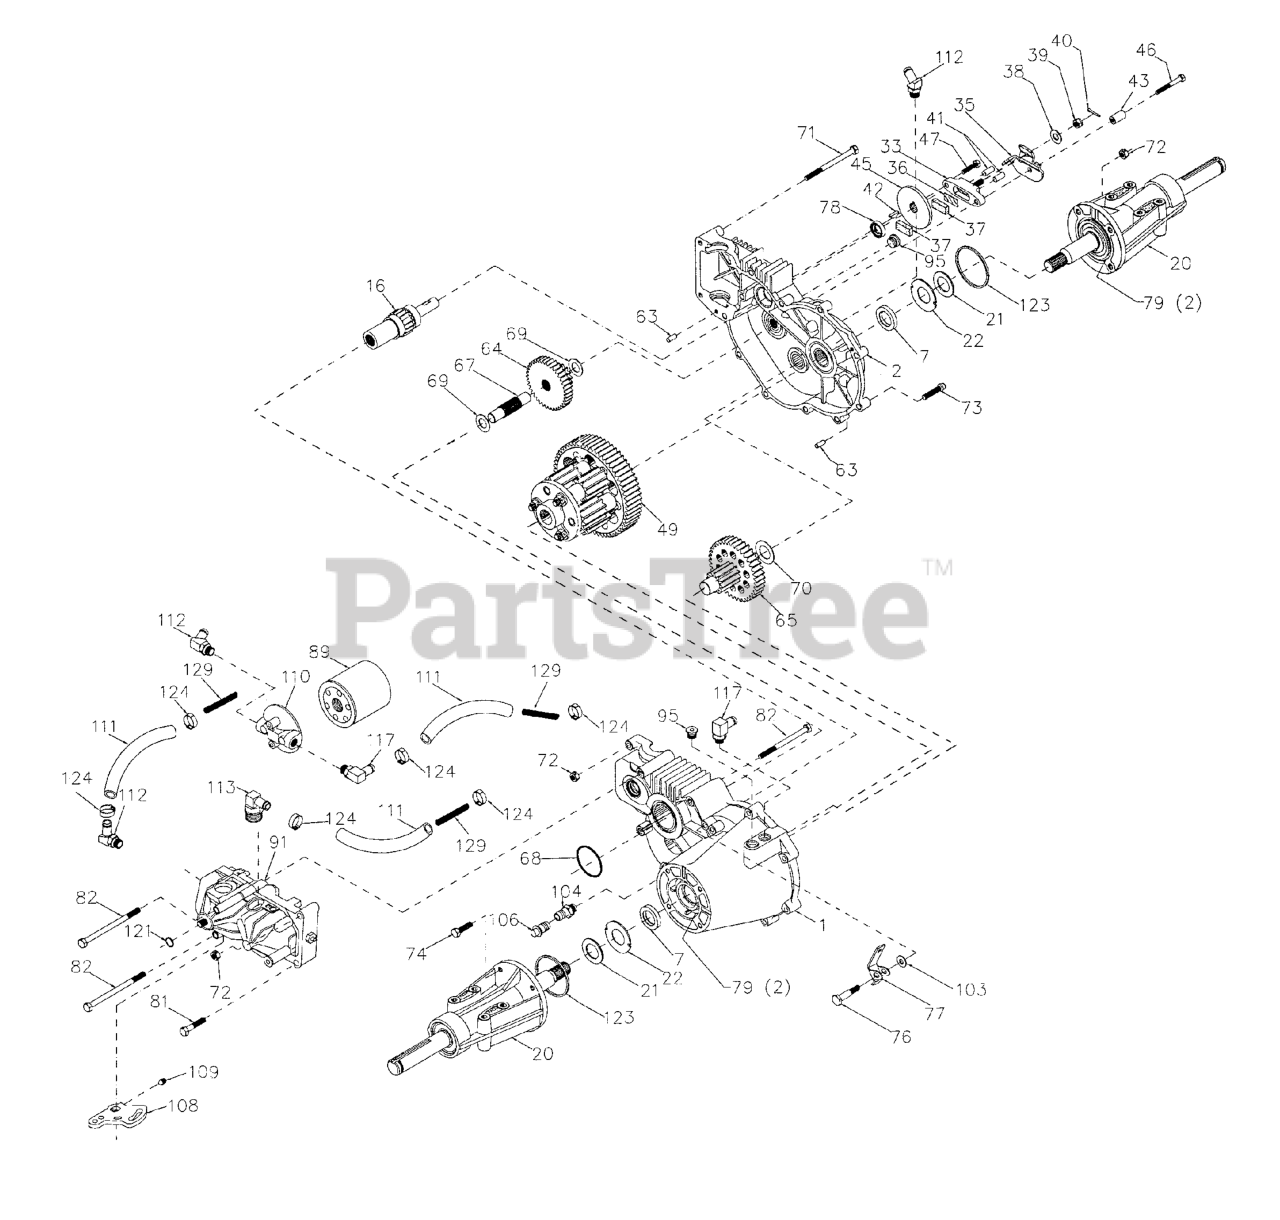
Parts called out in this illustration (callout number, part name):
1	Assembly, Housing, LH
2	Assembly, Housing, RH
7	Oil Seal .984 x 1.5 x .25
16	Brake Shaft Assembly
20	Axle Mounting Horn Assembly
21	Washer 1.0 x 1.63 x .08
22	Washer 1.0 x 2.06 x .09
33	Brake Yoke Assembly
35	Brake Arm
36	Puck Plate
37	Brake Puck
38	Washer 7/8 O.D. x 7/16 x .060
39	Nut, Castle 5/16-24
40	Cotter Pin
41	Brake Actuating Pin
42	Hi Pro Key
45	Brake Disc
46	Bolt 1/4-20 x 1-1/2
47	Bolt 1/4-20 x 1
49	Differential Assembly
63	Dowel Pin
64	Reduction Gear, 14 Teeth to 38 Teeth
65	Final Drive Pinion Assembly
67	Jackshaft
69	Washer 5/8 X 1-5/32
70	Washer 7/8 X 1-1/2
71	Bolt, Hex 5/16-18 x 3.5
72	Locknut, Hex 5/16-18
73	Bolt, Hex 5/16-18 x 1-1/2
74	Hex Cap Screw 5/16-18 x 1
76	Shoulder Bolt
77	Freewheel Actuating Arm
78	Oil Seal .625 x 1.0 x .25
79	Grease (10 oz. Tube)
81	Bolt, Hex 5/16-18 x 1-3/4
82	Bolt 5/16-18 x 4-1/2
89	Filter, Spin On
91	Pump, BDU-10L-122
95	Plug, Straight Thread
96	60° 7/18 SAE x 5/16 Fitting
104	Vent Cap Assembly
106	Fitting O-Ring Assembly
108	Control Arm
109	Set Screw
110	Filter Head
111	Hose 1/2"
112	Fitting, 1/2" Beaded 90° 7/8 SAE
113	Fitting, 1/2" Beaded 60° 9/16
117	Fitting, 1/2" Beaded 90° 9/16
124	Pinch Clamp
129	Spring, Long
